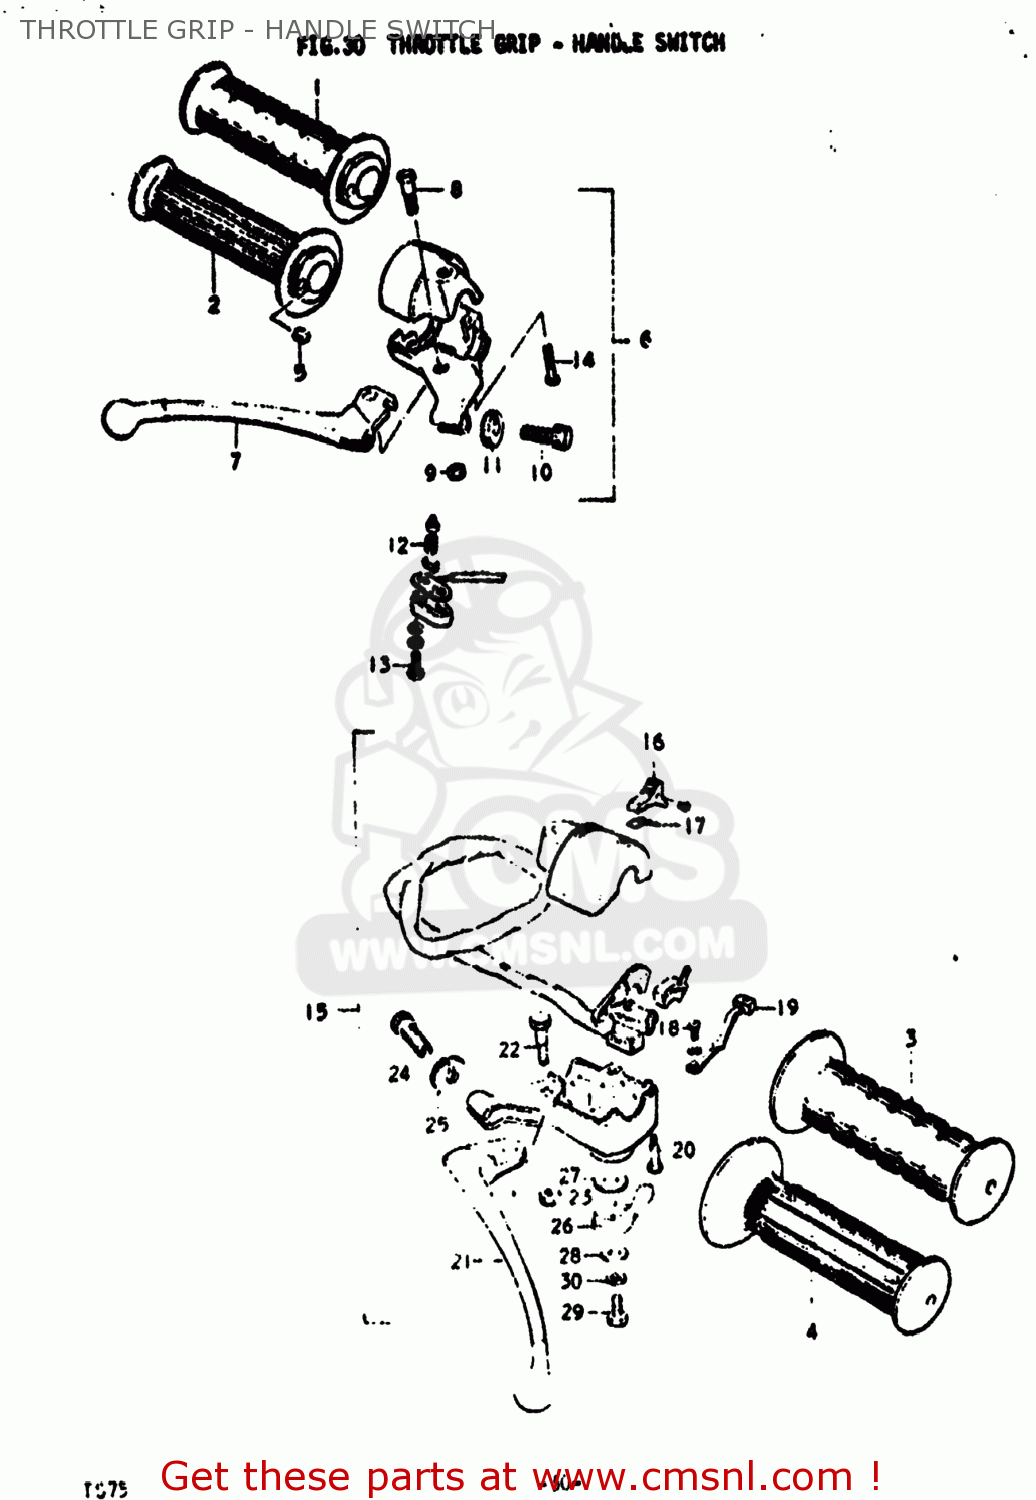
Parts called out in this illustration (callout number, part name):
1	GRIP,THROTTLE
2	GRIP,THROTTLE
3	GRIP
4	GRIP,LEFT
5	PIECE,THROTTLE END
6	LEVER/SWITCH ASSEMBLY,BRAKE
7	LEVER ASSEMBLY,ADJUST
8	BOLT
9	NUT
10	ADJUSTER,CABLE
11	NUT,CABLE ADJUSTER
12	SPRING
13	SCREW
14	SCREW
15	LEVER ASSEMBLY
16	KNOB,HANDLE SWITCH
17	PLATE,SWITCH KNOB
18	SCREW
19	KNOB,TURN SIGNAL SWITCH
20	SCREW
21	LEVER,CLUTCH
22	BOLT
23	NUT
24	ADJUSTER,CABLE
25	NUT,CABLE ADJUSTER
26	LEVER,STARTER
27	WASHER,ADJUSTER
28	WASHER,STARTER LEVER
29	BOLT
30	LOCK WASHER
